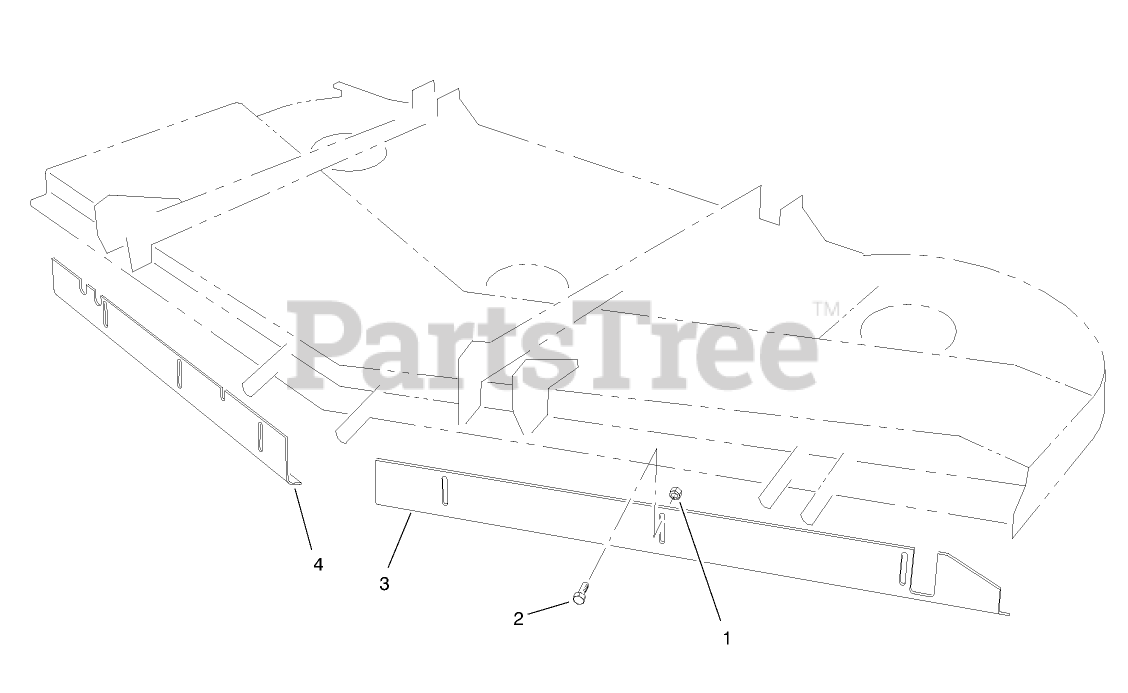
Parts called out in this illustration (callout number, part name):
1	NUT-HF
2	SCREW-HH
3	Baffle-Front LH
4	Baffle-Front RH
